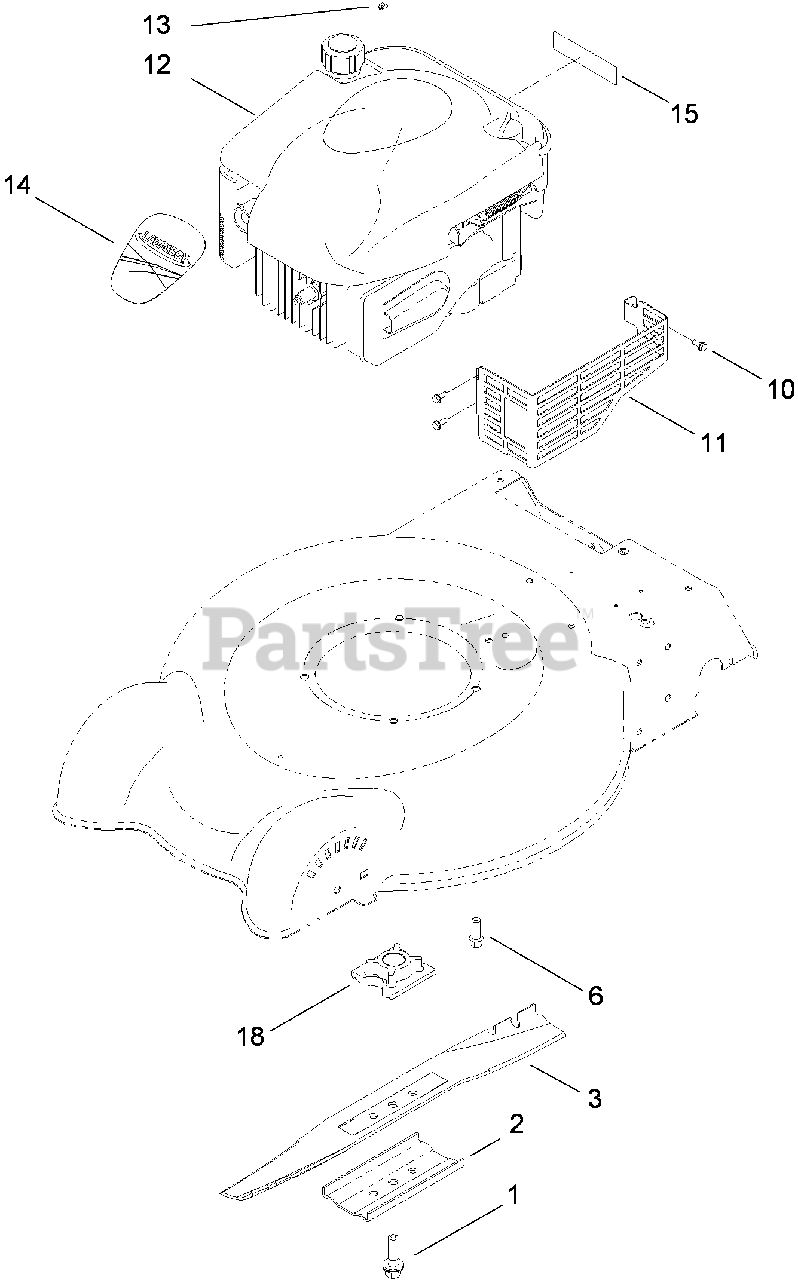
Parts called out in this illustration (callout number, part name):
1	BOLT-BLADE
2	SUPPORT-BLADE
3	BLADE-20 INCH
6	SCREW-TAPTITE
10	SCREW-TAPTITE
11	SHIELD-MUFFLER
13	STOP-ROPE
14	DECAL-SHROUD
15	DECAL-ARRESTER, SPARK
18	RETAINER-BLADE
